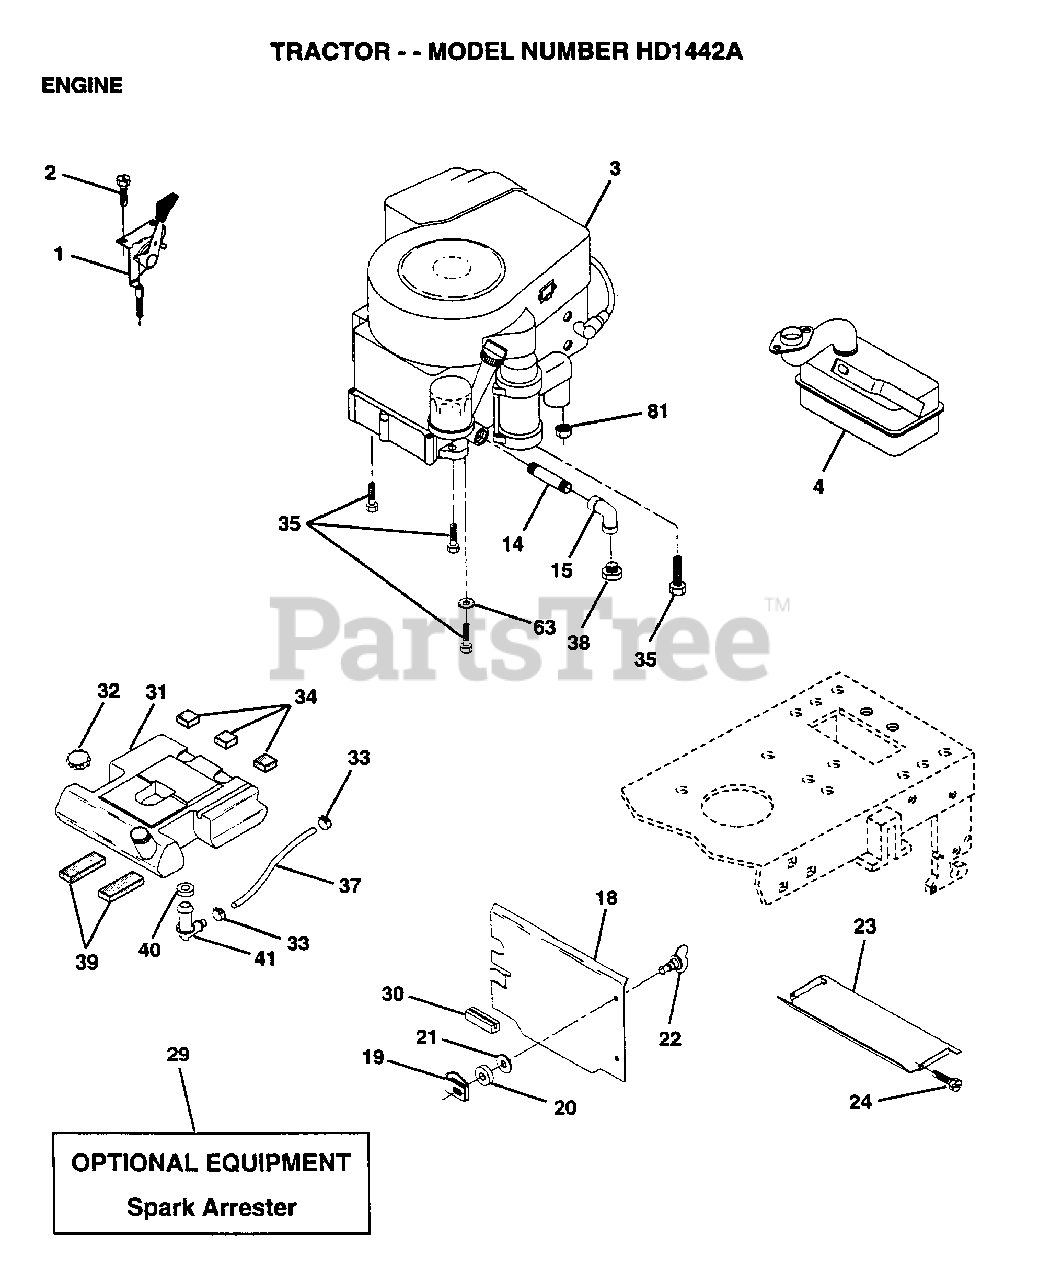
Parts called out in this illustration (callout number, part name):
1	CONTROL THROTTLE
2	SCREW LT
3	ENGINE ONAN 14 ELITE
4	MUFFLER EXHAUST
14	PIPE NIPPLE
15	ELBOW
18	SHIELD HEAT
19	RECEPTACLE LT
20	RETAINER LT
21	WASHER
22	STUD.1/4.TURN
23	HEAT SHIELD
24	SCREW
32	CAP ASM FUEL
33	HOSE CLAMP
34	PAD-SPACER LT
35	SCREW
37	FUEL LINE T
39	PAD IDLER TI
40	BUSHING OUTLET T
41	STEM.TANK.FUEL
63	LOCKWASHER.5/16.E
81	NUT
